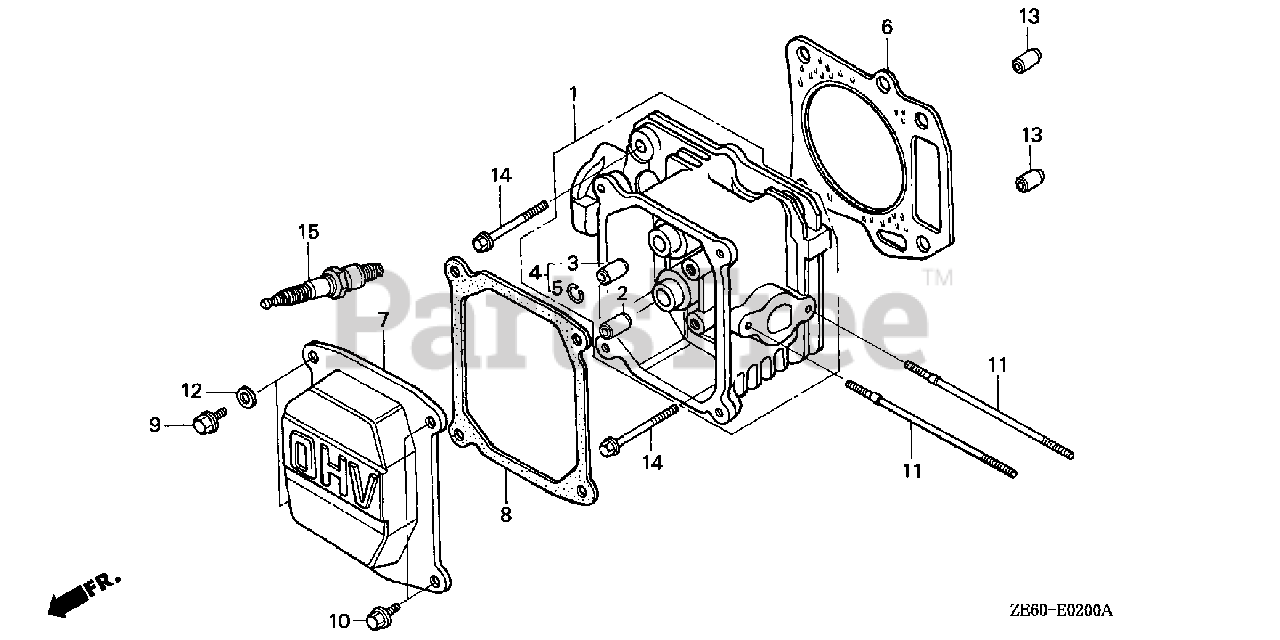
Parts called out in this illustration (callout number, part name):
1	CYLINDER HEAD
2	GUIDE, VALVE (OVER SIZE)
4	GUIDE, EX. VALVE (OVER SIZE)
5	CLIP, VALVE GUIDE
6	GASKET, CYLINDER HEAD
7	COVER, HEAD
8	GASKET, HEAD COVER
9	BOLT, FLANGE (6X14) (CT200)
10	BOLT, FLANGE (6X12) (CT200)
11	BOLT, STUD (6X112)
11	BOLT, STUD (6X109)
13	PIN, DOWEL (10X16)
14	BOLT, FLANGE (8X45)
15	SPARK PLUG (BPR4ES) (NGK)
15	SPARK PLUG (W14EPR-U) (DENSO)
15	SPARK PLUG (BPR5ES) (NGK)
15	SPARK PLUG (W16EPR-U) (DENSO)
15	SPARK PLUG (BPR6ES) (NGK)
15	SPARK PLUG (W20EPR-U) (DENSO)
